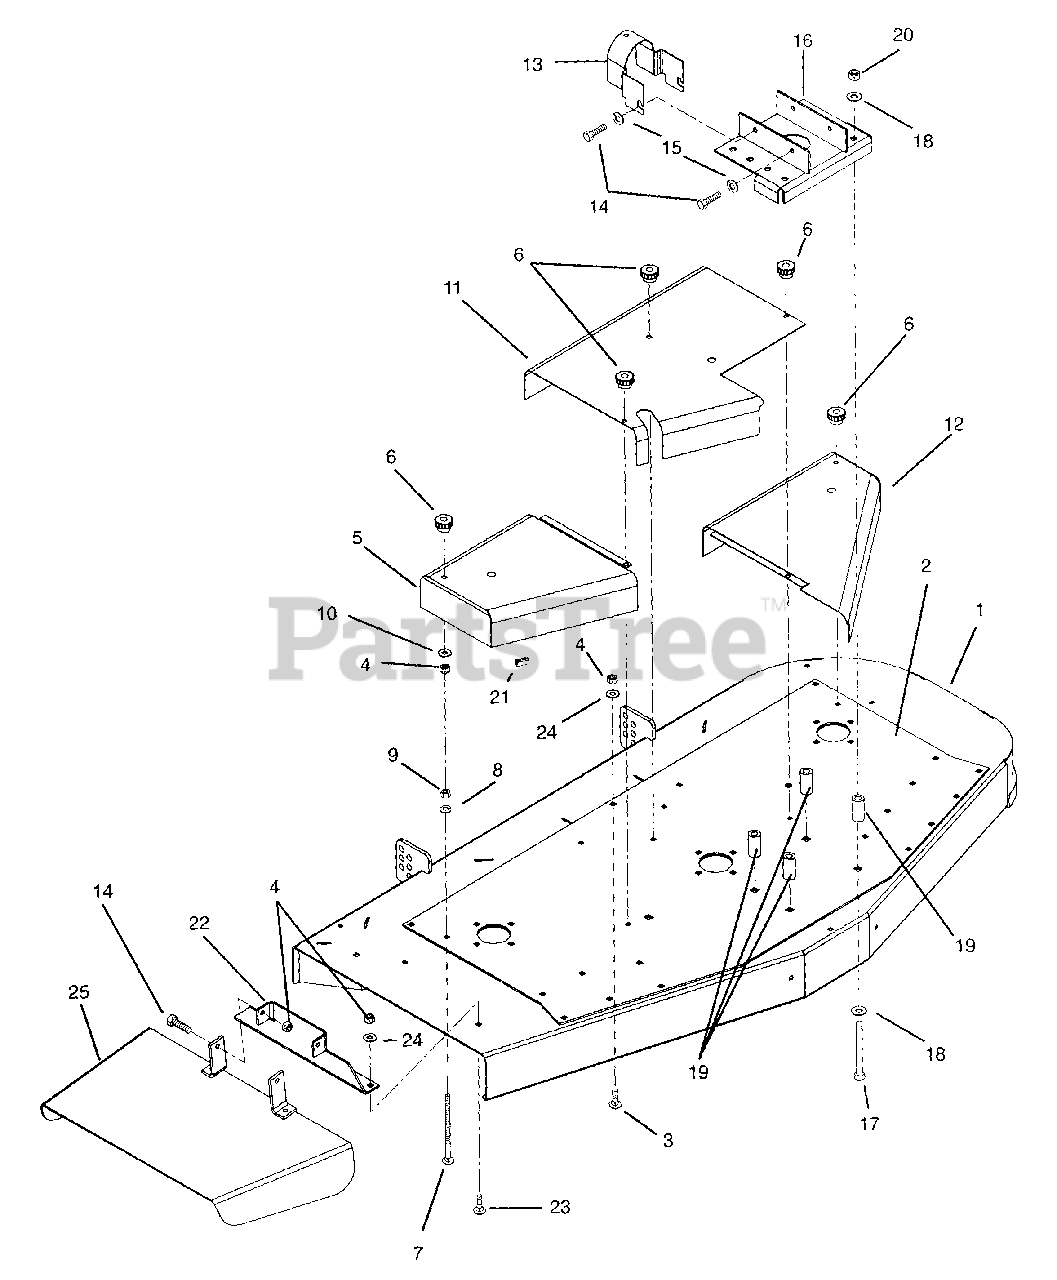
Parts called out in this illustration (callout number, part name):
1	Weldment, 60" Rear Discharge
2	Plate, Reinforcing 60" Deck
3	Bolt-Round Head Square Neck .38-16 x .75 Grade 2
4	Nut-Locking-Center .38-16
5	Cover, Belt Right Hand 60"
6	Knob
7	Bolt-Round Head Square Neck .312-18 x 4.0
8	Washer-Locking .31 x .078
9	Nut-Hex .31-18
10	Washer-Flat-Steel .38 x .875 x .083
11	Cover, Belt Middle 60"
12	Cover, Belt Left Hand 60"
13	Shield, U-Joint
14	Bolt-Hex .38-16 x 1.00 Grade 5
15	Washer-Lock .38 x .094
16	Weldment, Gearbox
17	Bolt-Hex .50-13 x 3.50 Grade 5
18	Washer-Flat-Steel .531 x 1.06 x .095
19	Spacer .562 x 1.00 x 2.00
20	Nut-Locking-Center .50-13
21	Trim Bumper
22	Bracket, Discharge Chute
23	Bolt-Round Head Square Neck .38-16 x 1.00 Grade 2
24	Washer-Flat-Steel .406 x .812 x .065
25	Weldment, Discharge Chute 60"
